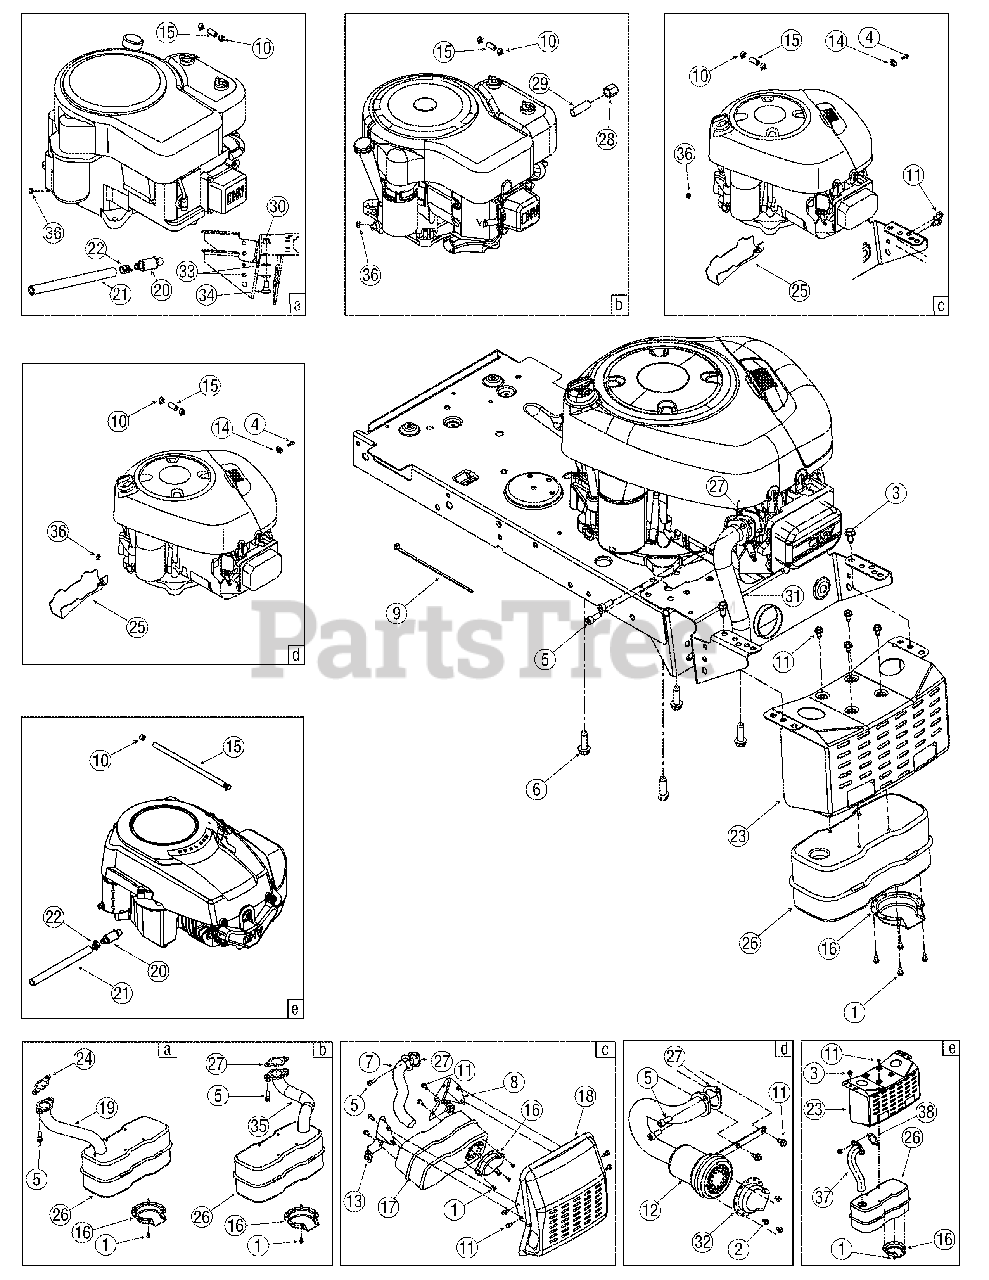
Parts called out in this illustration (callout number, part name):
1	Screw, #8-18 x .50
2	Screw, #8-18 x .375
3	Self-tapping Screw, 5/16-18, .625
4	Screw, #10-32, .625
5	Socket Cap Screw, 5/16-18, .625
6	Self-tapping Screw, 3/8-16, 1.25
7	Exhaust Pipe
9	Cable Tie, 7.4"
10	Hose Clamp, .490
11	Screw, 1/4-20, 0.500
12	Muffler, Bug
15	Fuel Line Hose
16	Muffler Deflector
17	Muffler, Single Inlet
19	Exhaust Pipe
20	Oil Drain Valve
21	Oil Drain Hose
22	Oil Drain Cap
24	Exhaust Gasket
25	Oil Drain Sleeve
26	Muffer, Single Inlet
27	Exhaust Gasket
28	Oil Drain Cap, 3/8-18
29	Oil Drain Pipe, 3/8-16, 2.0
30	Flange Lock Nut, 3/8-16
31	Exhaust Pipe
32	Muffler Deflector
33	Flat Washer, .406 x .875 x .059
34	SHOULDER SCREW .498 DIA x .340
35	Exhaust Pipe
36	Hex Sems Nut, 1/4-20
37	Kohler Courage Exhaust Pipe
38	Gasket, Kohler Courage
